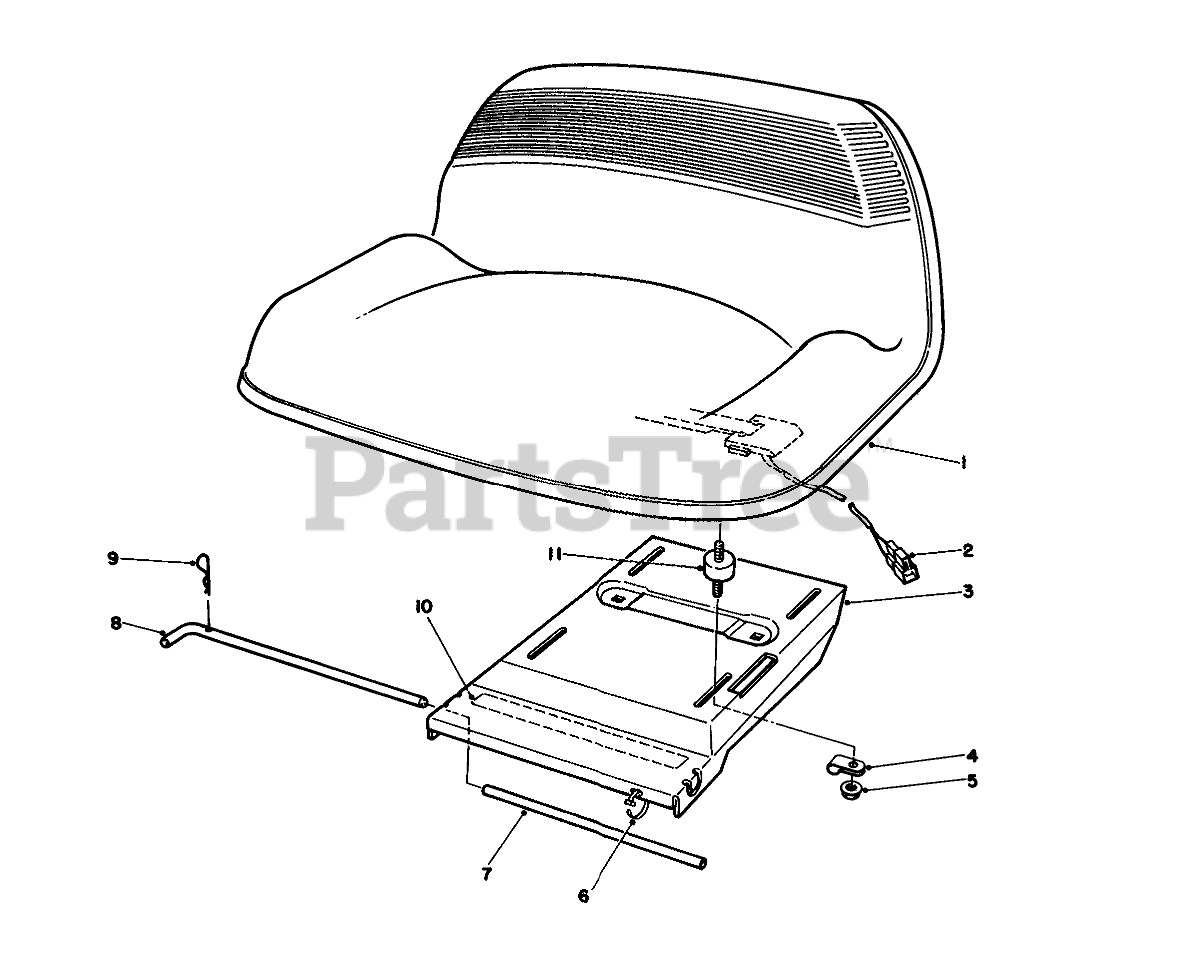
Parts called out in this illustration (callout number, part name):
1	Seat
2	SWITCH-SEAT
3	Base-Seat
4	CLAMP
5	NUT-HF
6	TIE-CABLE
7	TUBE-SEAT
8	ROD-SEAT BASE
9	PIN-COTTER
10	DECAL
11	ISOLATER-SEAT
